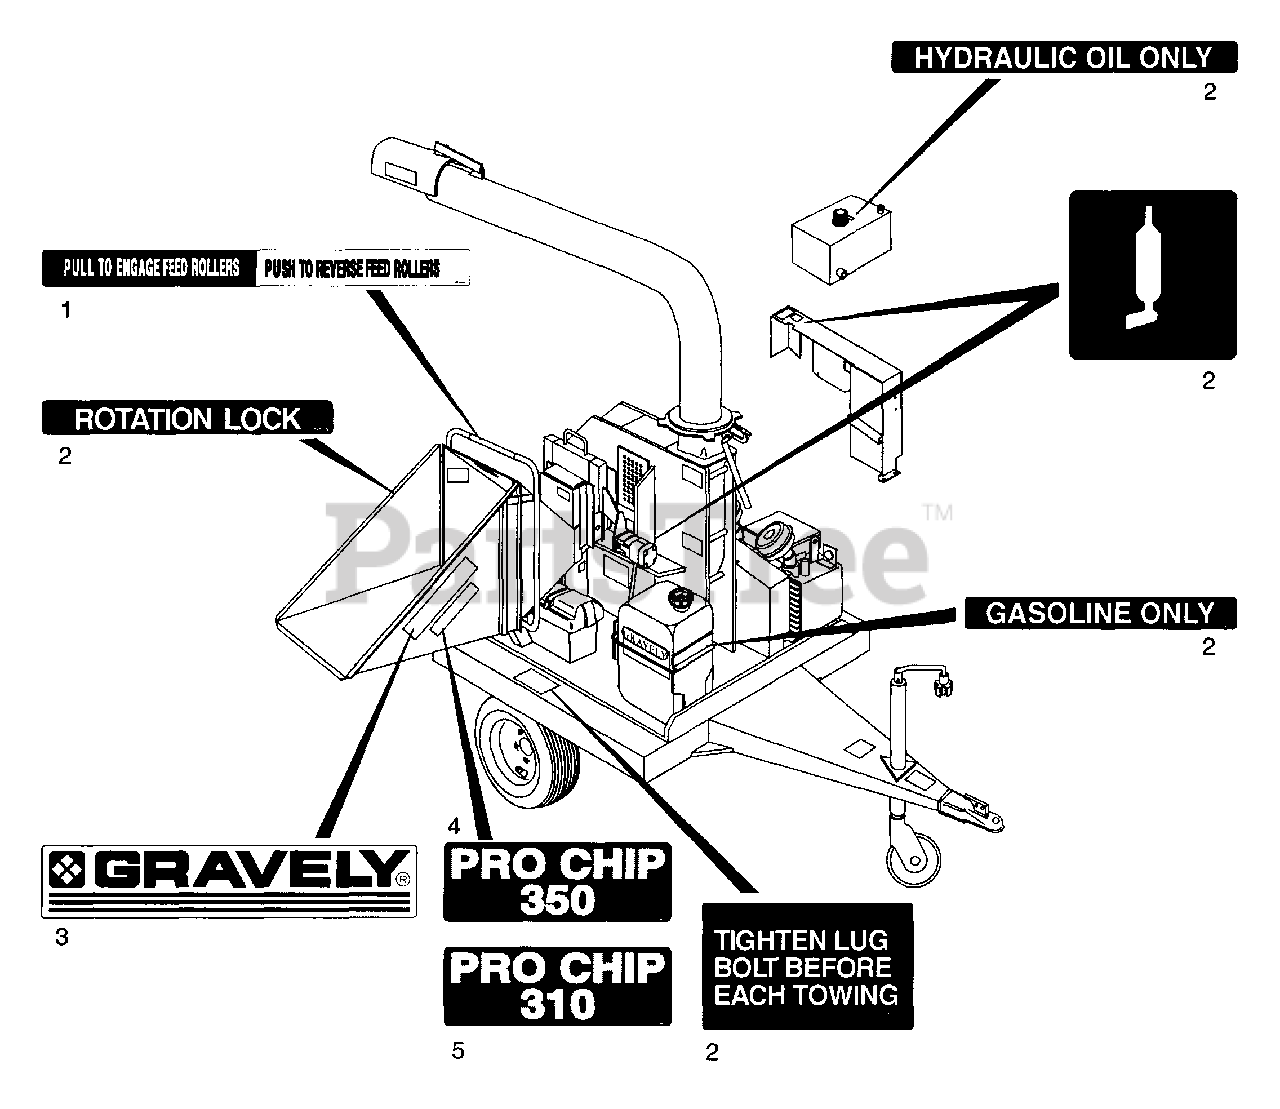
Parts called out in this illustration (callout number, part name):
1	Decal Set
2	Decal Set-Chipper Blk/Wht
3	Gravely Name/Logo/Stipe Decal
4	Decal, Pro Chip 350
5	Decal, Model Description 310
